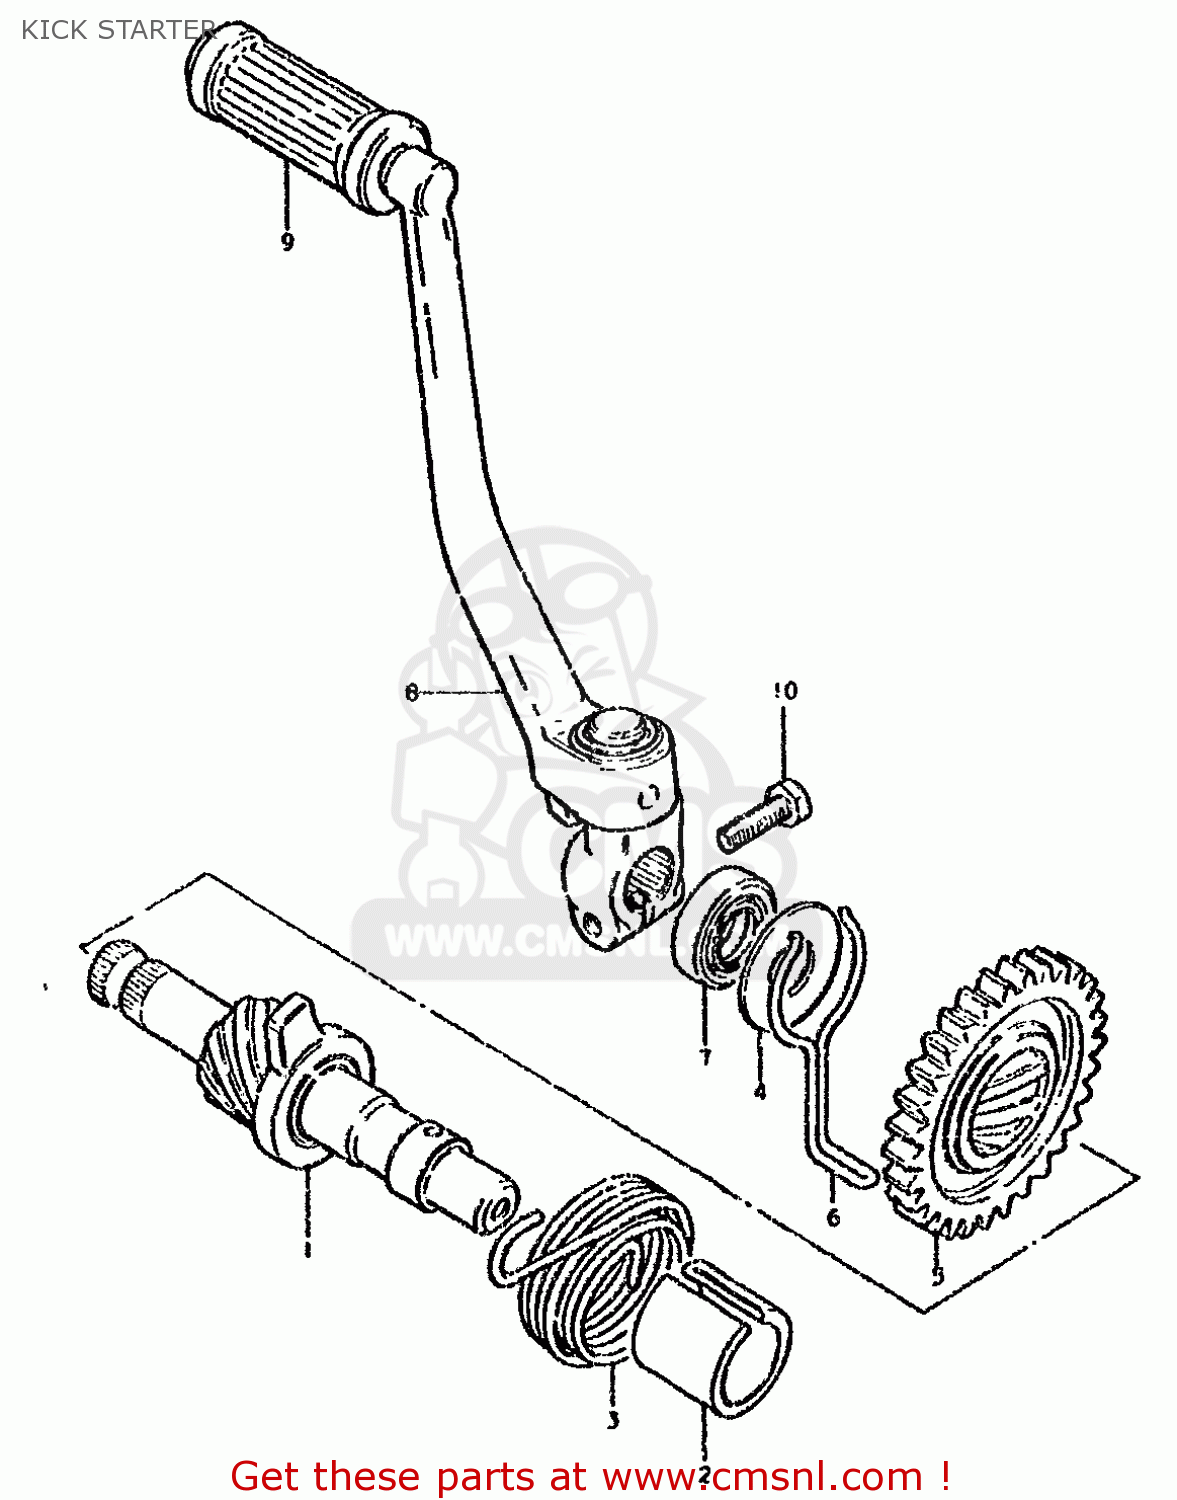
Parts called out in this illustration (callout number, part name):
1	SHAFT,KICK STARTER
2	GUIDE,KICK STARTER SFT SPRING
3	SPRING
4	WASHER
5	GEAR,KICK STARTER DRIVE(NT:30)
6	RETAINER,SNAP
7	SEAL,OIL(14X24X6)
8	LEVER ASSY,KICK STARTER
9	RUBBER,KICK STARTER PEDAL
10	BOLT
